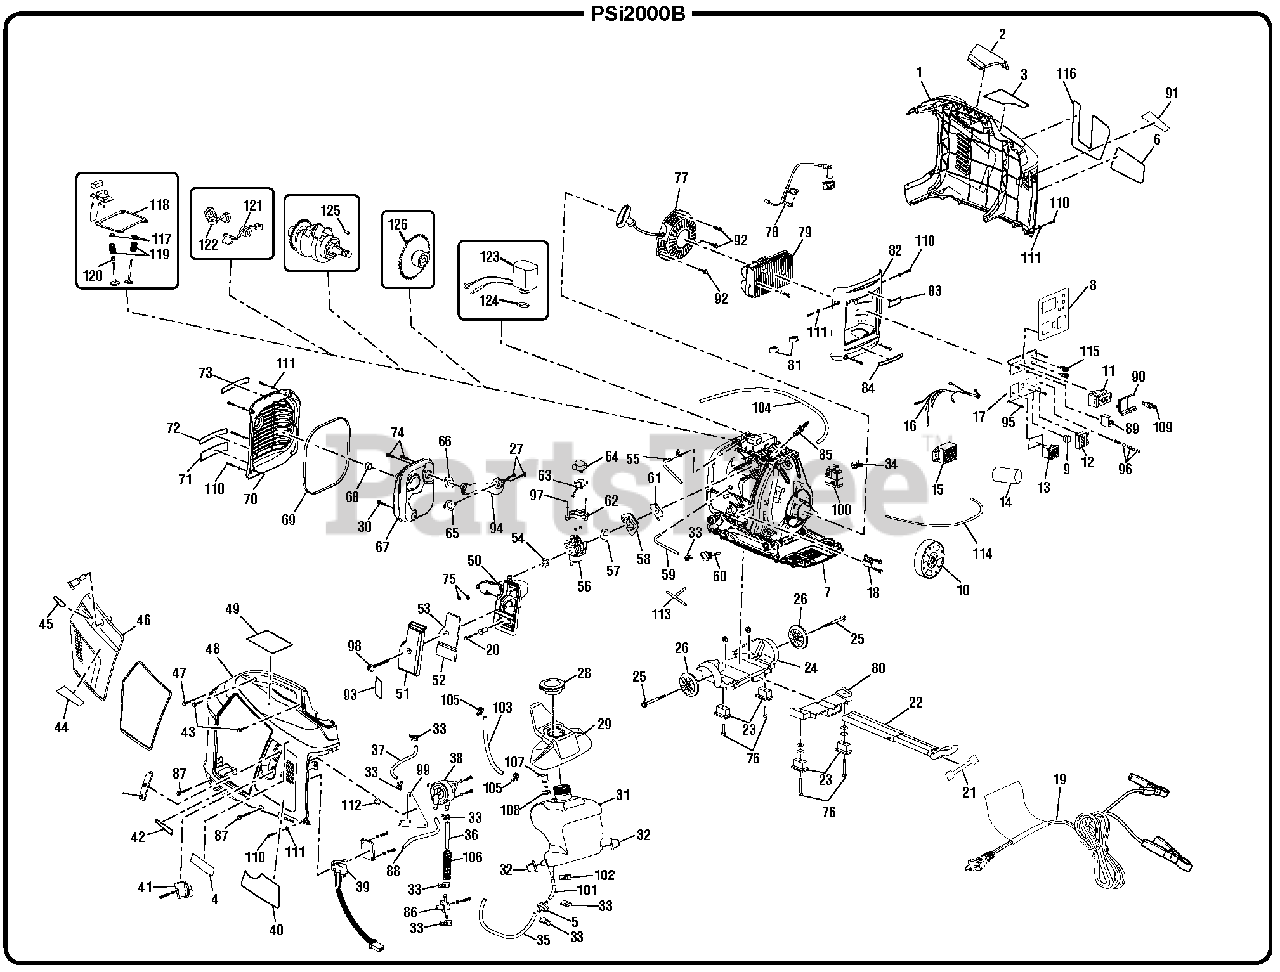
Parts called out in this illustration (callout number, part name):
1	Right Housing
2	Spark Plug Access Cover
3	Danger / E85 Label
4	Fire Danger Label
5	Fuel Filter
6	Features Label
7	Engine
8	Control Panel Label
9	Auto Idle Switch
10	Stator Assembly
11	AC Receptacle (120 Volt)
12	Ignition Module
13	DC Receptacle
14	Heat Shrink Tube
15	Bridge Rectifier
16	Wiring Harness (Internal)
17	Faceplate
18	Pick-Up Coil
19	Battery Charging Cable
20	Screw (M5 x 12 mm)
21	Handle Release Label
22	Handle Assembly
23	Rubber Foot
24	Rear Handle and Wheel Bracket
25	Wheel Mounting Bolt
27	Screw (M6 x 22 mm)
28	Fuel Cap Assembly
29	Fuel Overspill Guard
30	Screw (M6 x 65 mm)
31	Fuel Tank
32	Fuel Tank Support
33	Clamp (D9 x 12 mm)
34	Clamp (D7 x 08 mm)
35	Fuel Line (Filter to Valve, 6 mm x 10 mm)
36	Fuel Line (Valve to Pump, 6 mm x 10 mm)
37	Fuel Line (Pump to Carburetor, 6 mm x 10 mm)
38	Fuel Pump
39	Engine Shut Off Switch
40	Quick Start Label
41	Switch Handle
42	Lubricant Label
43	Bolt (M6 x 30 mm)
44	Logo Label (Left)
45	Choke Label
46	Maintenance Cover
47	Bolt (M6 x 100 mm)
48	Left Housing
49	CPSC Label
50	Air Filter Back
51	Air Filter Cover
52	Air Filter (Lower)
53	Air Filter (Upper)
54	Intake Gasket
55	Engine Breather Hose
56	Carburetor Assembly
57	Carburetor Gasket
58	Intake Seat
59	Vapor Hose (Engine To T-Fitting, 320 mm)
61	Insulator Gasket
62	Governor Bottom Cover
64	Governor Top Cover
65	Manifold Gasket
66	Muffler Gasket
68	Spark Arrestor
69	Muffler Cover Seal
70	Muffler Cover
71	Data Label
72	Combustion Label
73	Hot Surface Label
74	Screw (M6 x 45 mm)
75	Nut (M5)
76	Screw (M5 x 35 mm)
77	Recoil Starter Assembly
78	Ignition Coil
79	Inverter Module
80	Foot Brace (Front Handle)
81	Inverter Module Support
82	Control Panel Holder
83	Logo Label (Small)
84	Ground Warning Label
85	Spark Plug
86	Fuel Shut Off Valve
87	Screw (M6 x 140 mm)
88	Vapor Hose (T-Fitting To Fuel Pump)
89	Circuit Breaker (20 Amp)
90	Receptacle Cover
91	Logo Label (Right)
92	Screw (M6 x 16 mm)
93	Check Oil Label
94	Exhaust Pipe
95	Screw (M48x19 mm)
96	Washer (M5)
97	Screw (M5 x 8 mm)
98	Screw (M6x16 mm)
99	Fuel Pump Bracket
100	Carbon Canister
101	Fuel Line (Tank to Filter, 6 mm x 10 mm)
102	Clamp (D10 x 08 mm)
103	Vent Hose (Tank to Carbon Canister)
104	Vent Hose (Carbon Canister to Air-box)
105	Clamp (D7 x 08 mm)
106	Hose Supporting Spring
107	Fuel Tank Vent Valve
109	Reset Button
110	Screw (M5 x 15 mm)
111	Flat Washer (ID53 x OD10 x 05t)
113	T-Fitting Vapor Hose
114	Vapor Hose (T-Fitting To Engine Return)
115	Connector
116	Performance Label
117	Valve Retainer
118	Head Gasket
119	Valve spring
121	Intake Rocker Assembly
122	Exhaust Rocker Assembly
123	Oil Sensor
124	Oil Sensor Seal
125	Engine Shaft Key
126	Engine Cam
